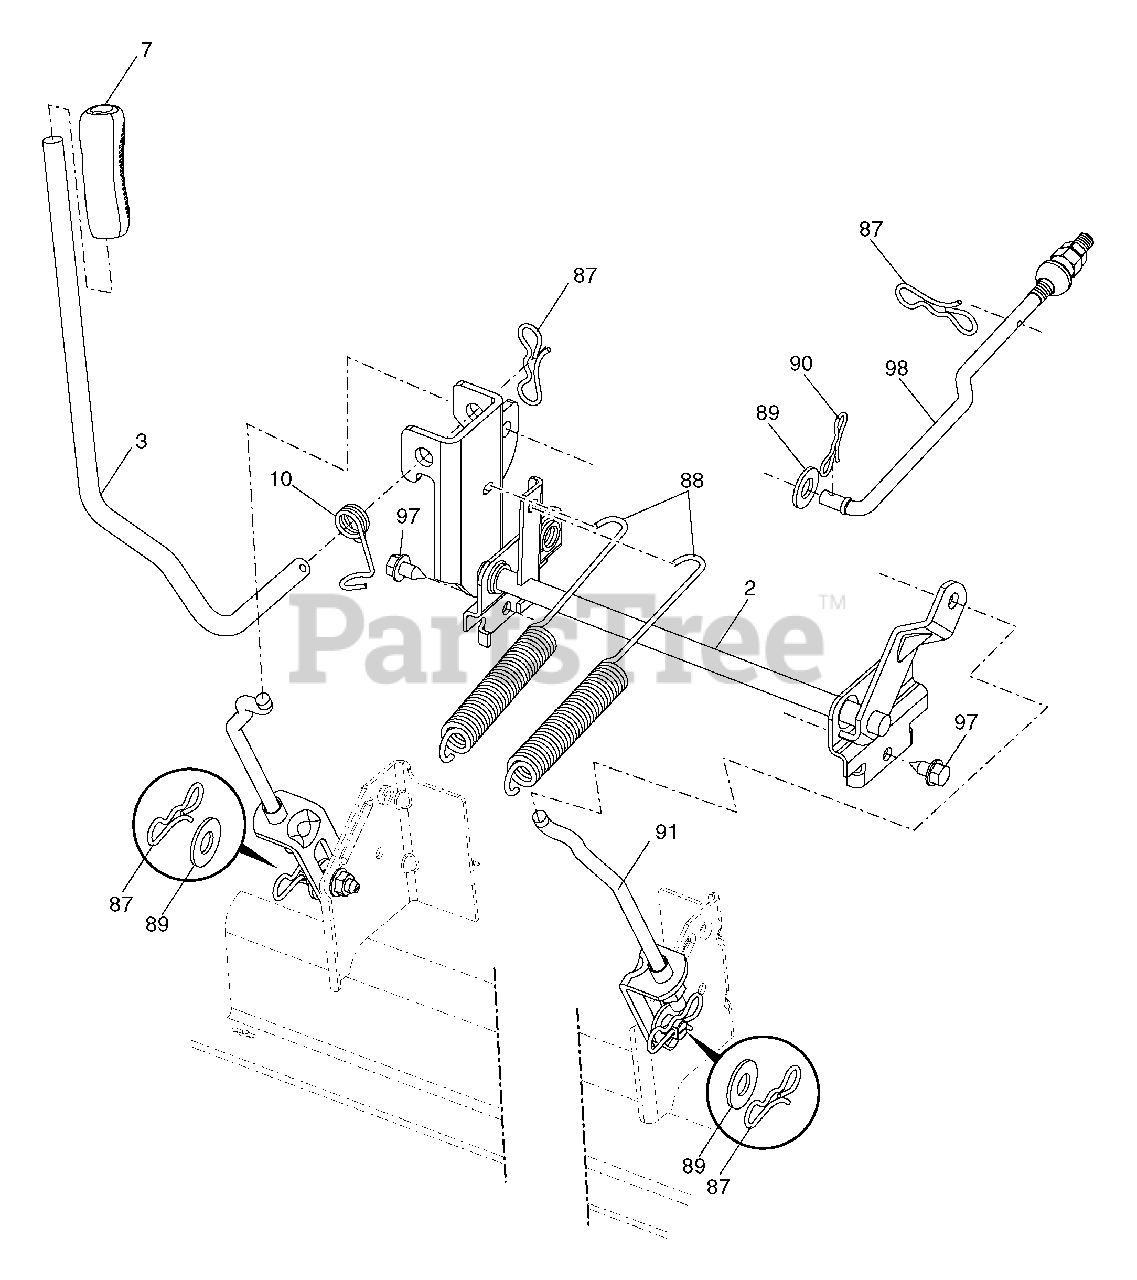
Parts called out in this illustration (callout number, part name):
2	Shaft Asm., Lift
3	Lever Asm., Lift Rh
7	Grip, Lever
10	Spring Torsion
87	Pin Cotter 7/16 Bow Tie Lock
88	Spring Lift Assist
89	Washer Clear Zinc
90	Pin Cotter 5/16 Bow Tie Lock
91	Link Lift Susp Mower Rear
92	Bracket Connect Link Lift
95	Bushing Alignment Link Lift
97	Screw 3/8-16 x .75 Smgml Tap/R.Z
98	Link Lift Susp. Front Mower
99	Bushing Spherical Susp Front
100	Nut Hex Jam ASF 7/16-20 unf
